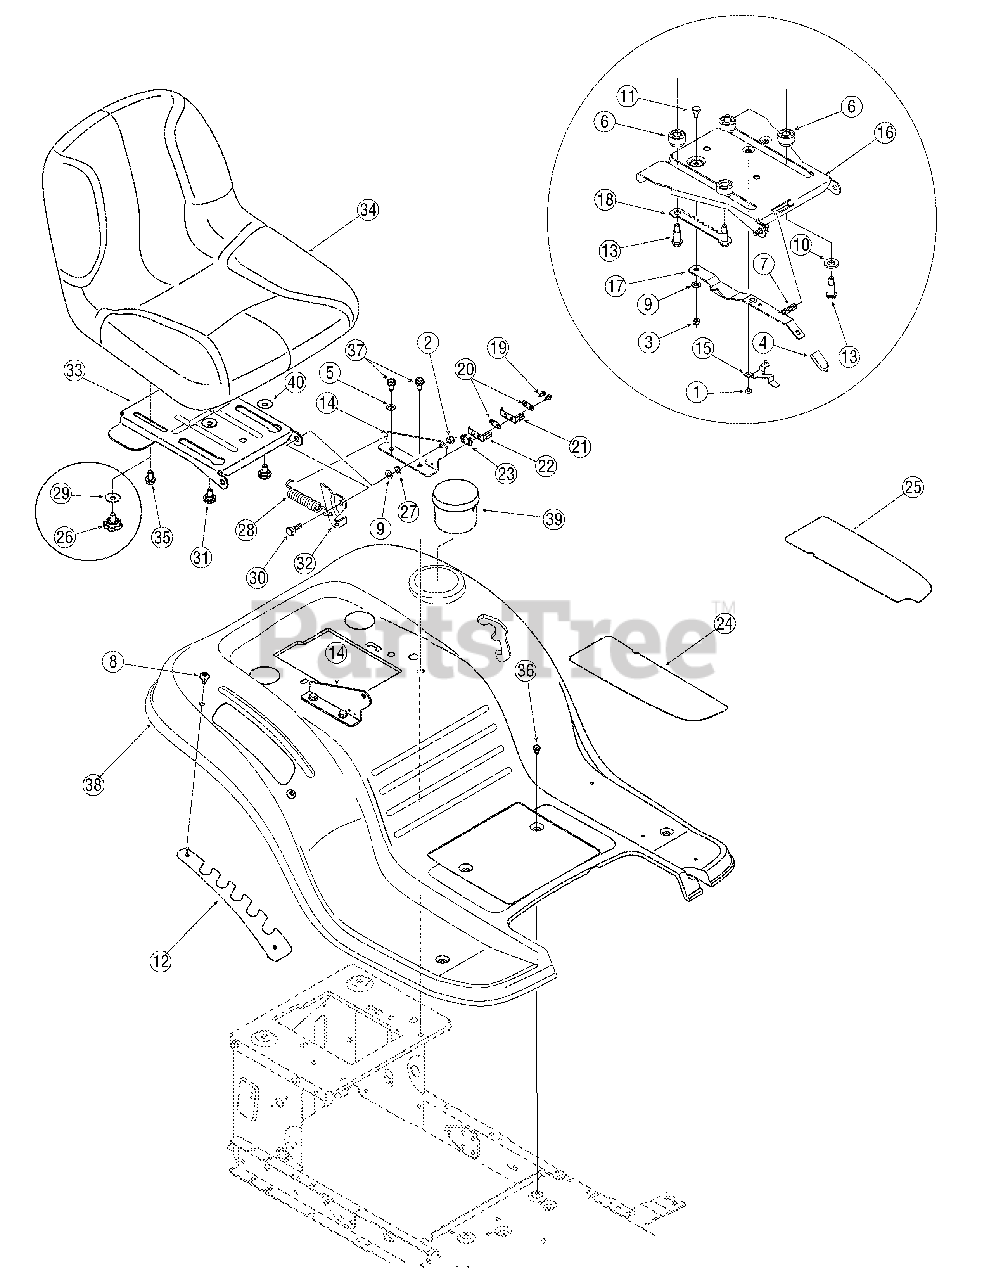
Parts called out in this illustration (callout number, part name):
1	Screw, #10-16, .375
2	Nut, Flange Lock, 5/16-18, GrF
3	Nut, Flange Lock, 1/4-20
4	Seat Adjuster Grip
5	Lock Washer, 5/16
6	Spacer
7	Compression Spring, .41 x 1.5
8	SCREW 1/4-20 x .500
9	FLAT WASHER
10	Wash, Flat, .531x 1.062 x.134
11	Screw, Shlder, .340 x .285,1/4-20
13	Screw, Shlder, .50 x .925, 3/8-16
15	Seat Stop
18	Seat Adjustment Selector
19	Screw, #8-18 x .50
20	Plate, Insulator
21	Spring Switch, Outer
22	Spring Switch, Inner
23	Plate, Insulator Boss
24	Foot Pad, Abrasive, RH
24	Foot Pad, Rubber RH
25	Foot Pad, Abrasive, LH
25	Foot Pad, Rubber LH
26	Knob, 3/8-16, .875
27	Nut, Speed, .3125 Id
28	Spring, Exten., .84 Dia x 4.6 Lg.
29	Washer, Flat, .406 x 1.00 x .030
30	Scr., Shlder, .437 x .268, 5/16-18
31	Screw, Shlder, .625 x .175, 3/8-16
32	Lift Bracket, Seat
34	Seat, Low, Black
34	Seat, Medium, Black
34	Seat, Low, Yellow
35	Screw, 3/8-16, .875
36	Screw, 1/4-20, 0.500
37	Screw, 5/16-18, 0.625
39	Cup Holder
40	Flat Washer, .406 x .875 x .059
40	Flat Washer, .395 x .62 x .063
